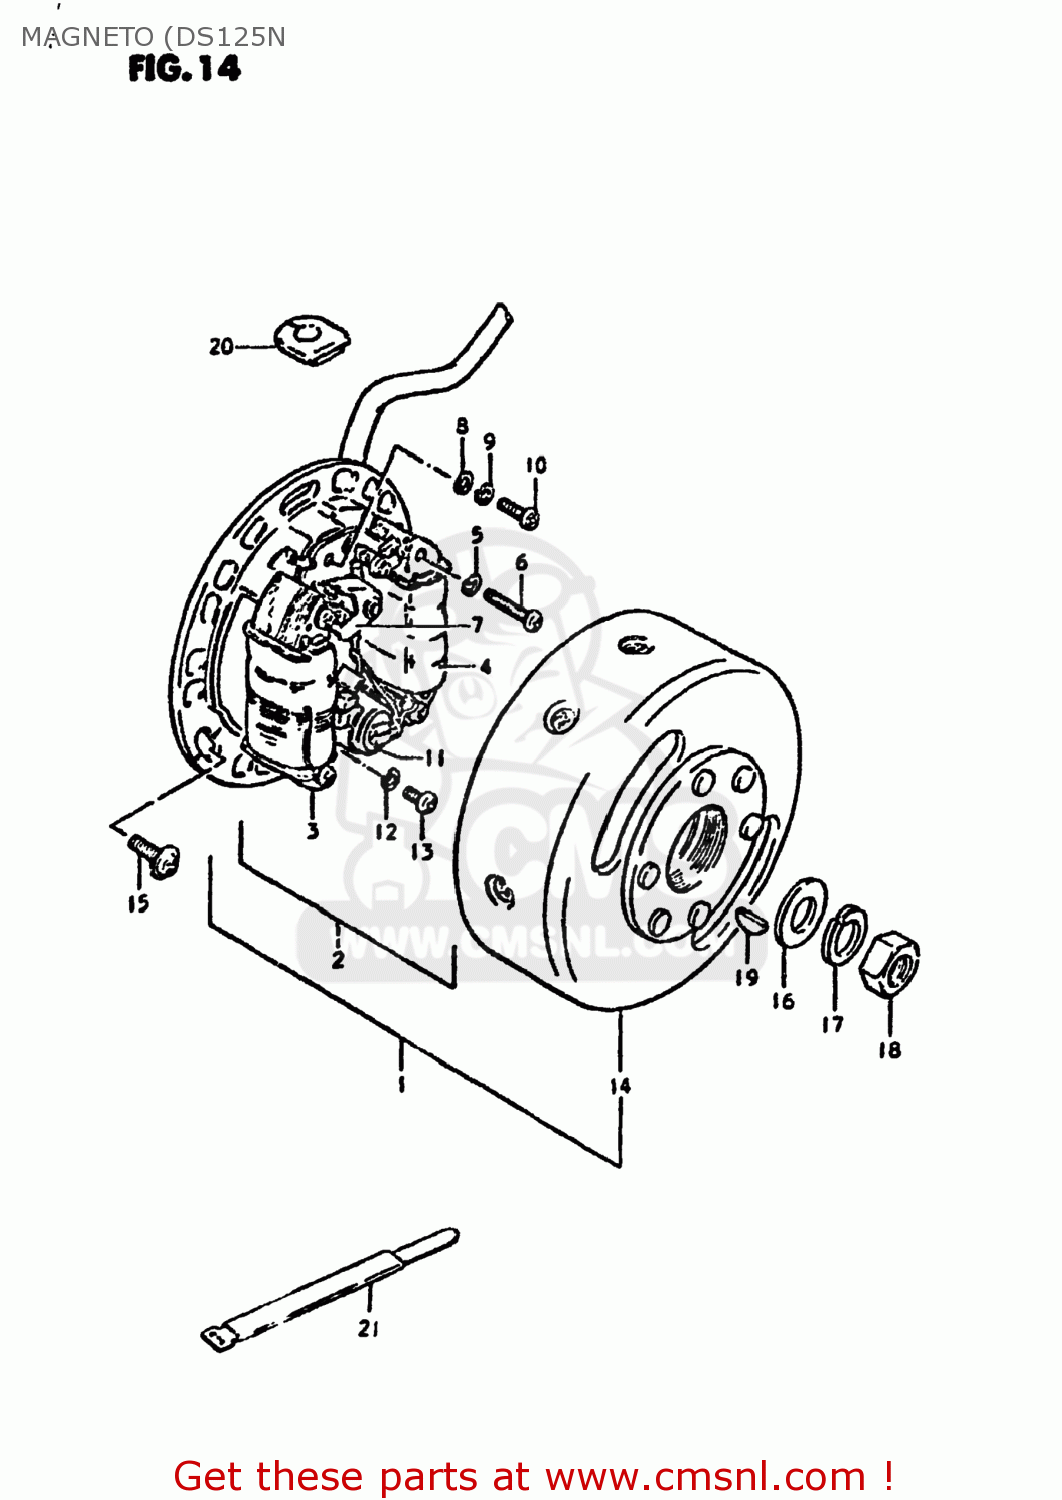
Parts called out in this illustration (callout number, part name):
1	MAGNETO ASSEMBLY
2	STATOR ASSEMBLY
3	COIL,LIGHTING
4	COIL,PRIMARY
5	LOCK WASHER
6	SCREW (4X30)
7	POINT ASSY,CONTACT
8	WASHER
9	LOCK WASHER
10	SCREW(4X10)
11	CONDENSER
12	LOCK WASHER
13	SCREW
14	ROTOR ASSEMBLY
15	SCREW(5X14)
16	WASHER
17	LOCK WASHER
18	NUT (10MM)
19	KEY
20	GROMMET
21	CLAMP
